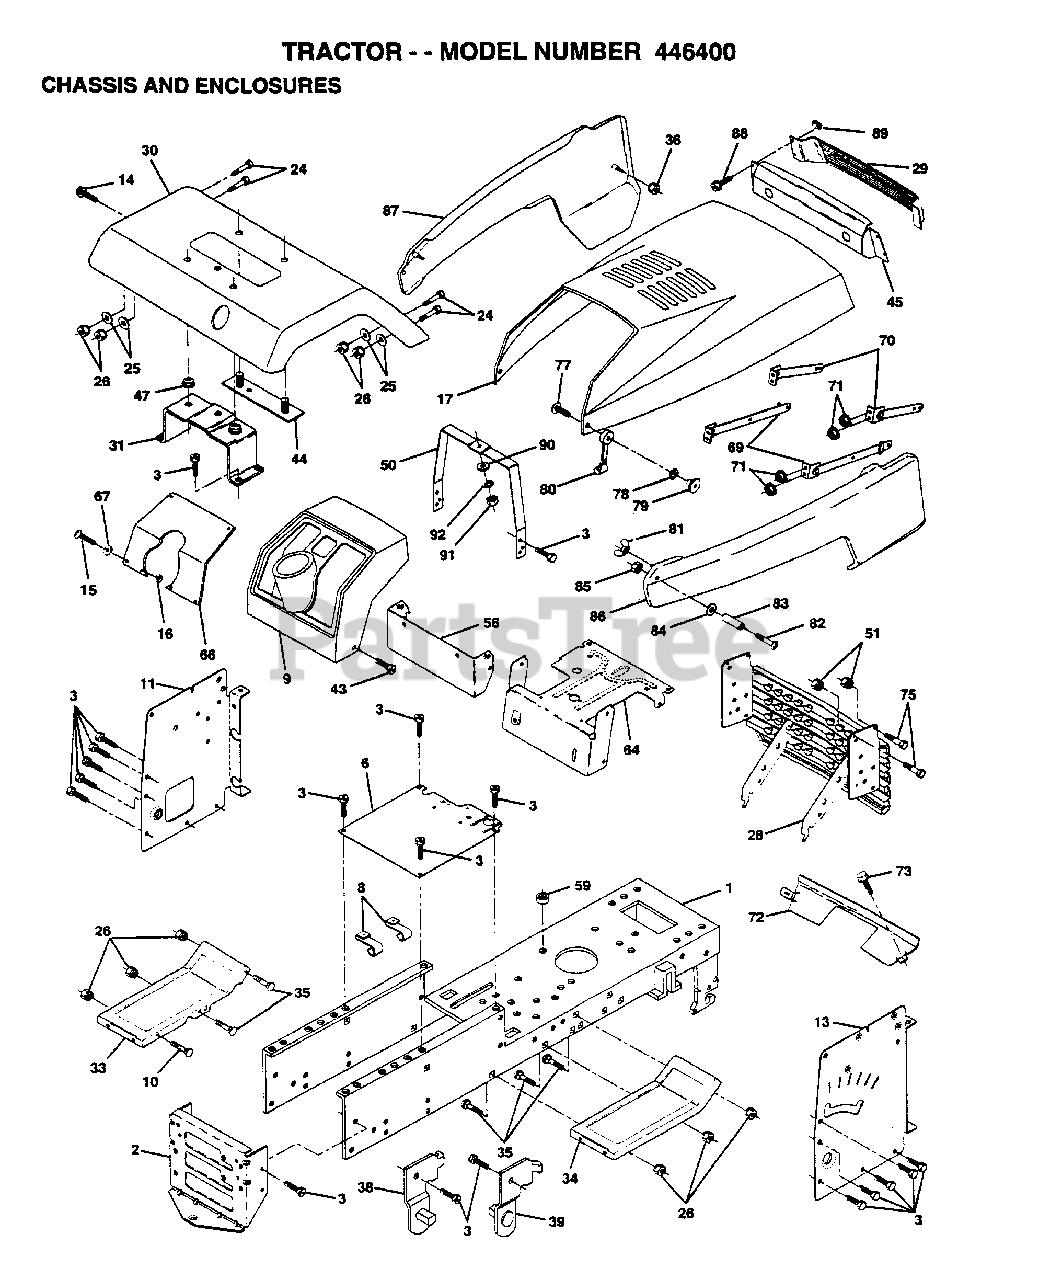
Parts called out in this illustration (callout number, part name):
1	CHASSIS.WLD.11GA
3	SCREW
8	"CLIP,INSULATOR"
9	DASHBOARD BLACK
11	PANEL.DASH.LH.
13	PANEL.DASH.RH.
14	SCREW LT
15	SCREW
20	PLATE.SUPT.BATTER
24	BOLT
25	WASHER
26	NUT
29	LENS LT
30	FENDER.PNT.
31	BRKT.ASM.FENDER
35	BOLT
36	PAL NUT LT
38	BRACKET ASM LH
39	BRACKET ASM RH
43	SCREW GTV
44	STRAP ASM FENDER
47	NUT-PUSH YT
50	DASH.SUPT.YP/HUSQ
51	NUT
56	DASH.EXT.PNT.
65	BOLT
66	PLATE SLKSCR YP
67	WASHER
71	NUT HXKEP 1/4X20
72	STRAP.GRILLE.PNT.
73	SCREW CRT
76	BOLT
77	SCREW
78	LOCKWASHER
79	WELDNUT
80	HOOD LATCH T
82	SCREW
83	SPACER LT
84	WASHER
86	PANEL SIDE RH
89	"""J"" FASTENER LT"
90	WASHER PM
92	LOCKWASHER
96	NUT
